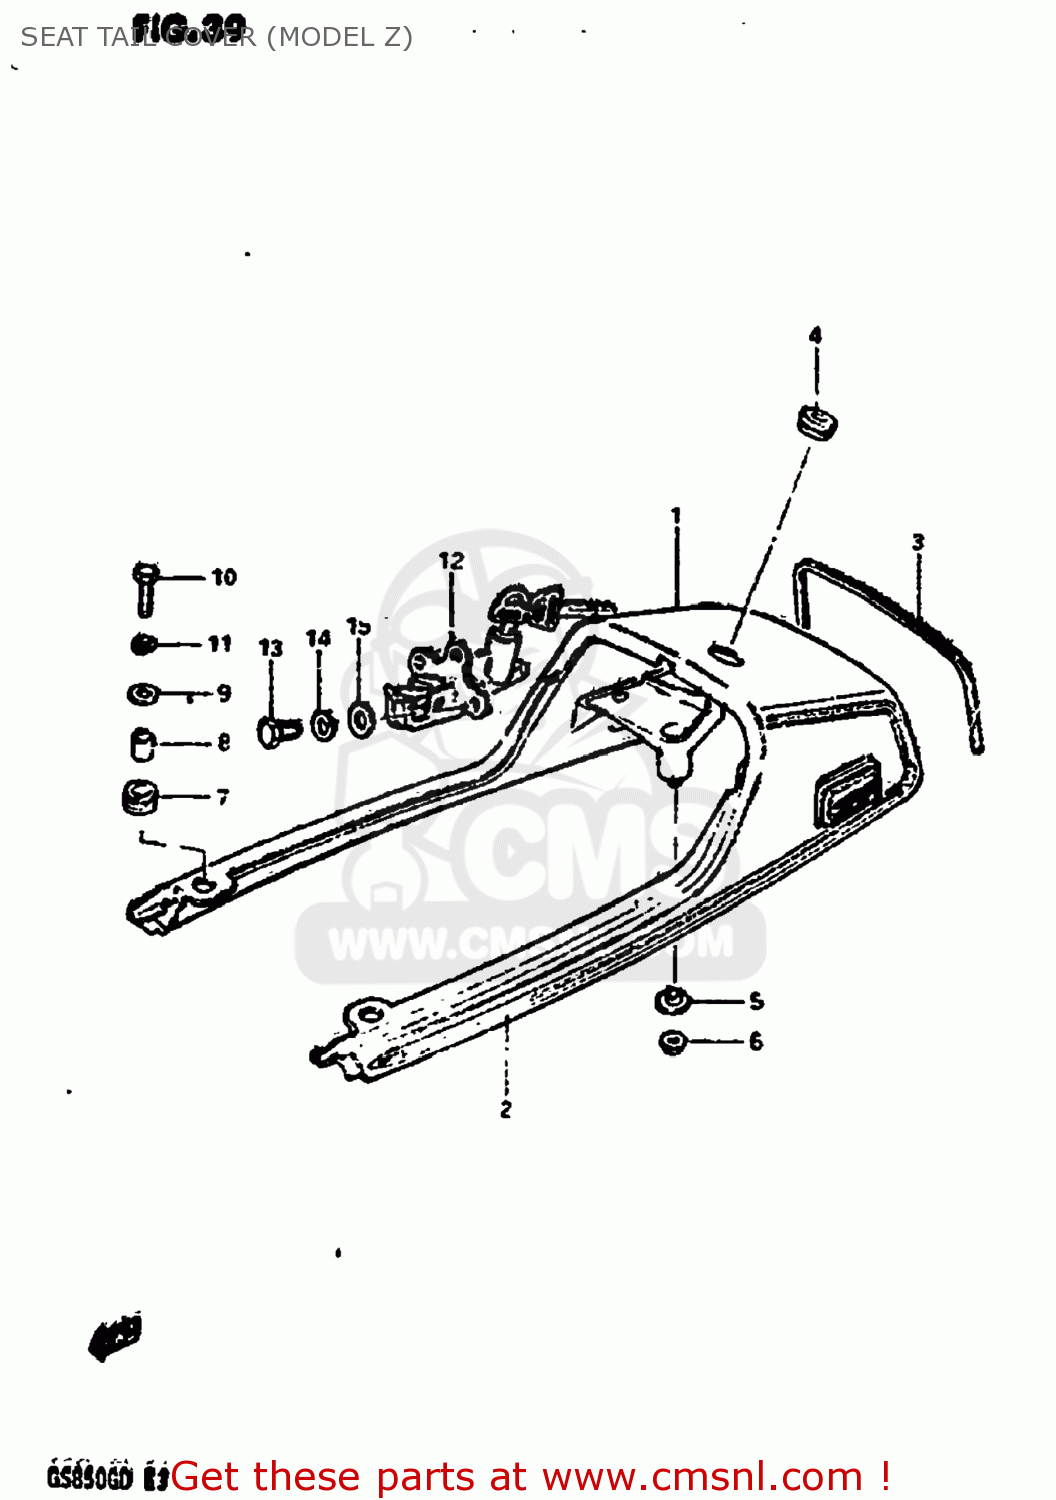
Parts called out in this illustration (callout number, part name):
1	COVER SET,SEAT TAIL
2	TAPE SET,SEAT TAIL COVER
3	MOLDING,SEAT TAIL COVER
4	GROMMET,SEAT LOCK HOLE
5	WASHER
6	NUT 6MM
7	CUSHION
8	SPACER (7X10X12)
9	WASHER (6.5X24X1.6)
10	BOLT
11	LOCK WASHER
12	LOCK SET,SEAT
13	BOLT
14	LOCK WASHER
15	WASHER
